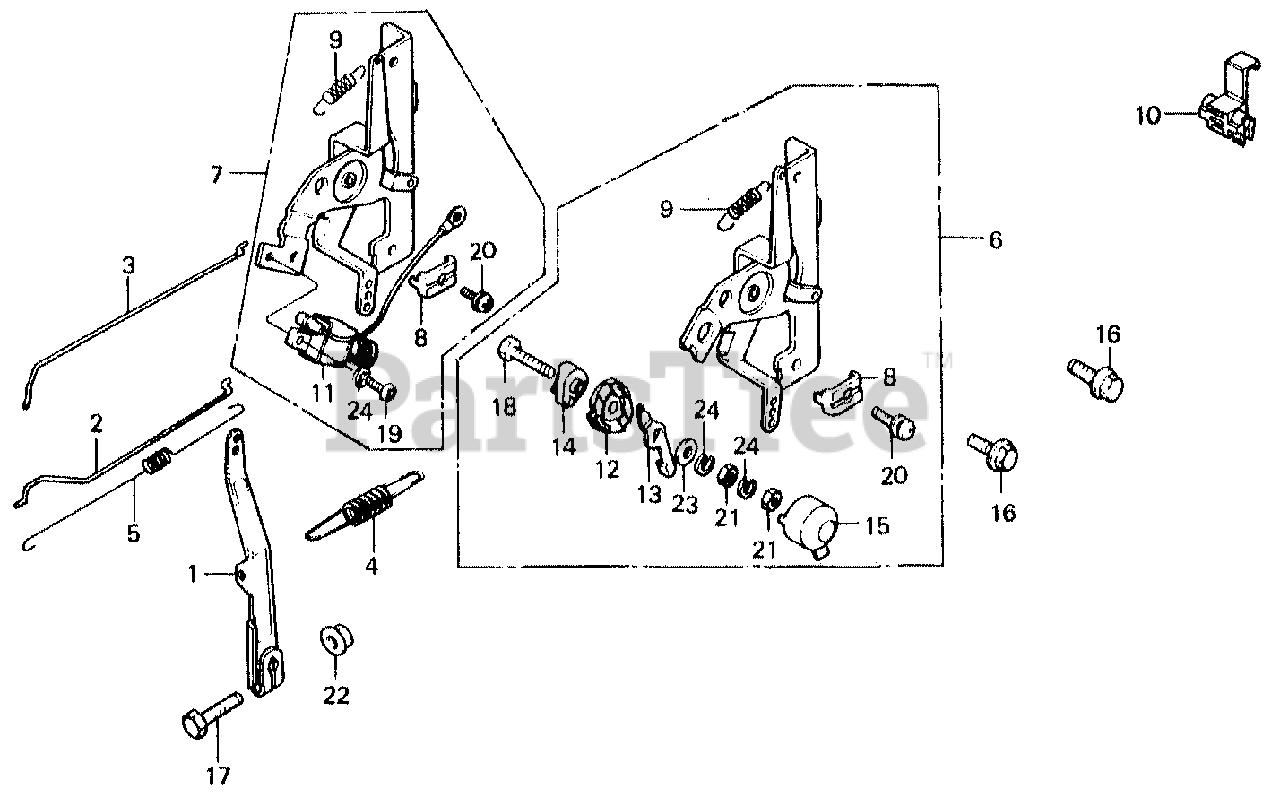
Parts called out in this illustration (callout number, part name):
1	ARM, GOVERNOR
2	ROD, GOVERNOR
3	ROD, CHOKE
4	SPRING, GOVERNOR
5	SPRING, THROTTLE RETURN
6	CONTROL ASSY.
8	HOLDER, CABLE
9	SPRING, CABLE RETURN
10	CONNECTOR, WIRE
12	BASE, SWITCH
13	CONTACT, SWITCH
14	WASHER, INSULATOR
16	BOLT, FLANGE (6X16)
17	BOLT, GOVERNOR ARM
18	BOLT, HEX. (4X20)
20	SCREW-WASHER (5X16)
21	NUT, HEX. (4MM)
22	NUT, FLANGE (6MM)
23	WASHER, PLAIN (4MM)
24	WASHER, SPRING (4MM)
